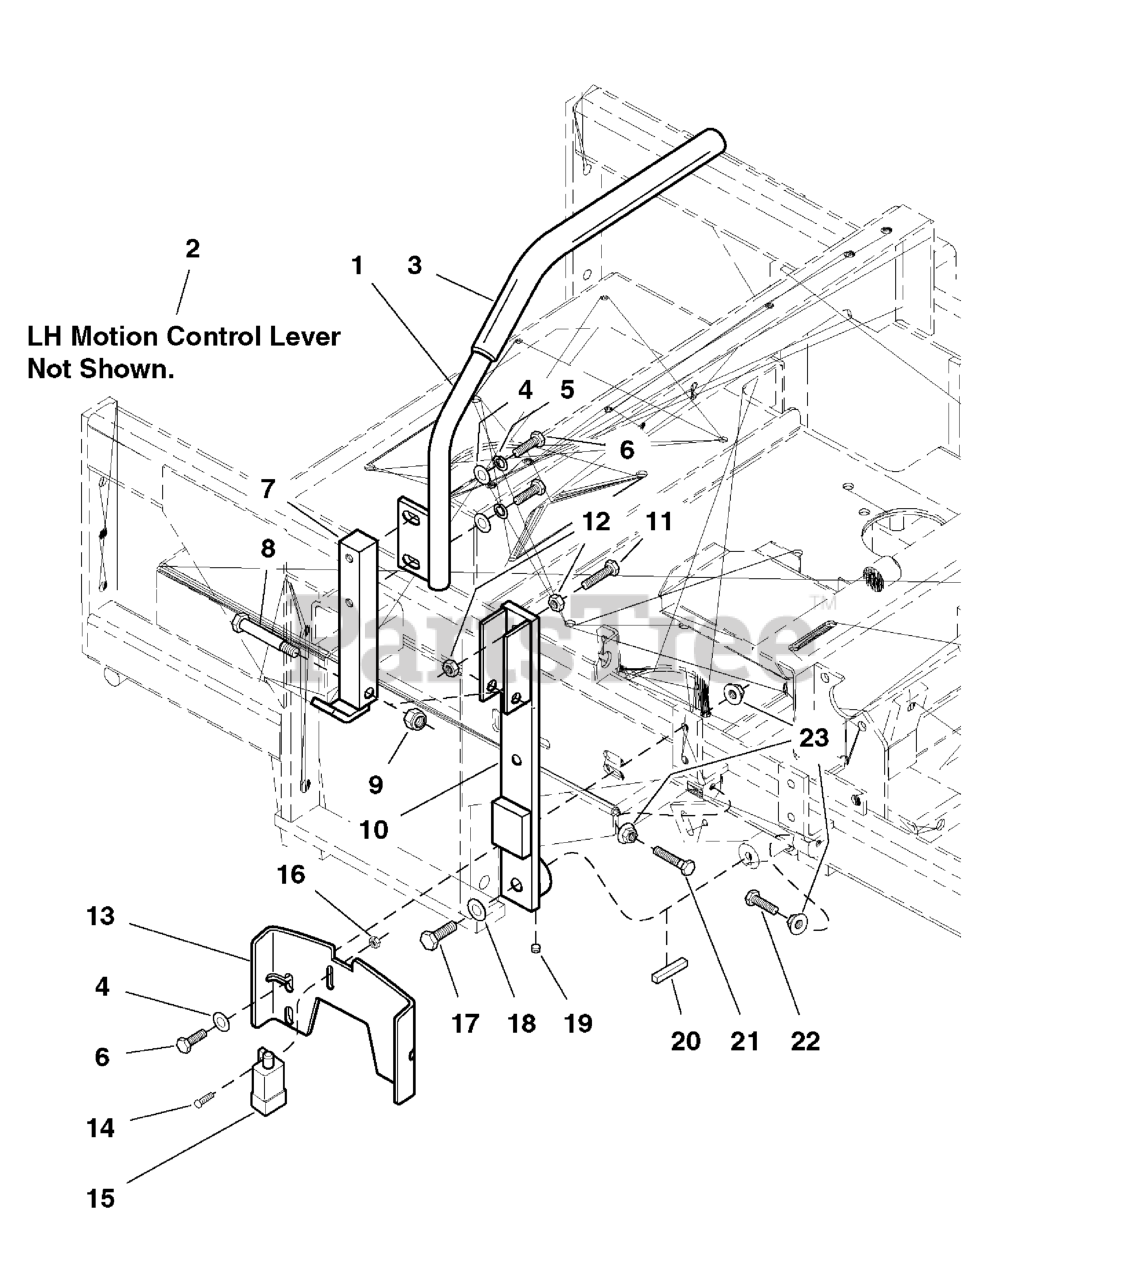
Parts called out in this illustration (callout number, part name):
1	MOTION CONTROL LEVER-RH
3	GRIP, Foam
4	WASHER, 5/16" SAE
5	WASHER, 5/16 LOCK CZ
6	BOLT, 5/16-18 X 3/4 GD5
7	CONTROL LEVER BASE
8	BOLT, 3/8-16 X 2, GD5, CZ
9	NUT, 3/8-16 HEX NYLON LOCK
10	CONTROL LEVER MOUNT
11	BOLT, 5/16-18 X 1 GD5 YZ
12	NUT, 5/16-18 HEX
13	NEUTRAL LOCK PLATE
14	SCREW, #10-24 X 1 RS, CZ
15	SWITCH, PLUNGER, N.O./N.C.
16	NUT, #10-24 Hex
17	BOLT, 3/8-16 x 1-1/4 w/ patch
18	WASHER, 3/8 SAE
19	SET SCREW, 5/16-18 x 1/4 w/ patch
20	KEY, 1/4 SQ. X 1
21	BOLT, 5/16-18 x 1-3/4
22	BOLT, 5/16-18 x 1-1/4
23	NUT, 5/16-18 HEX SERRATED FLANGE (SMALL)
